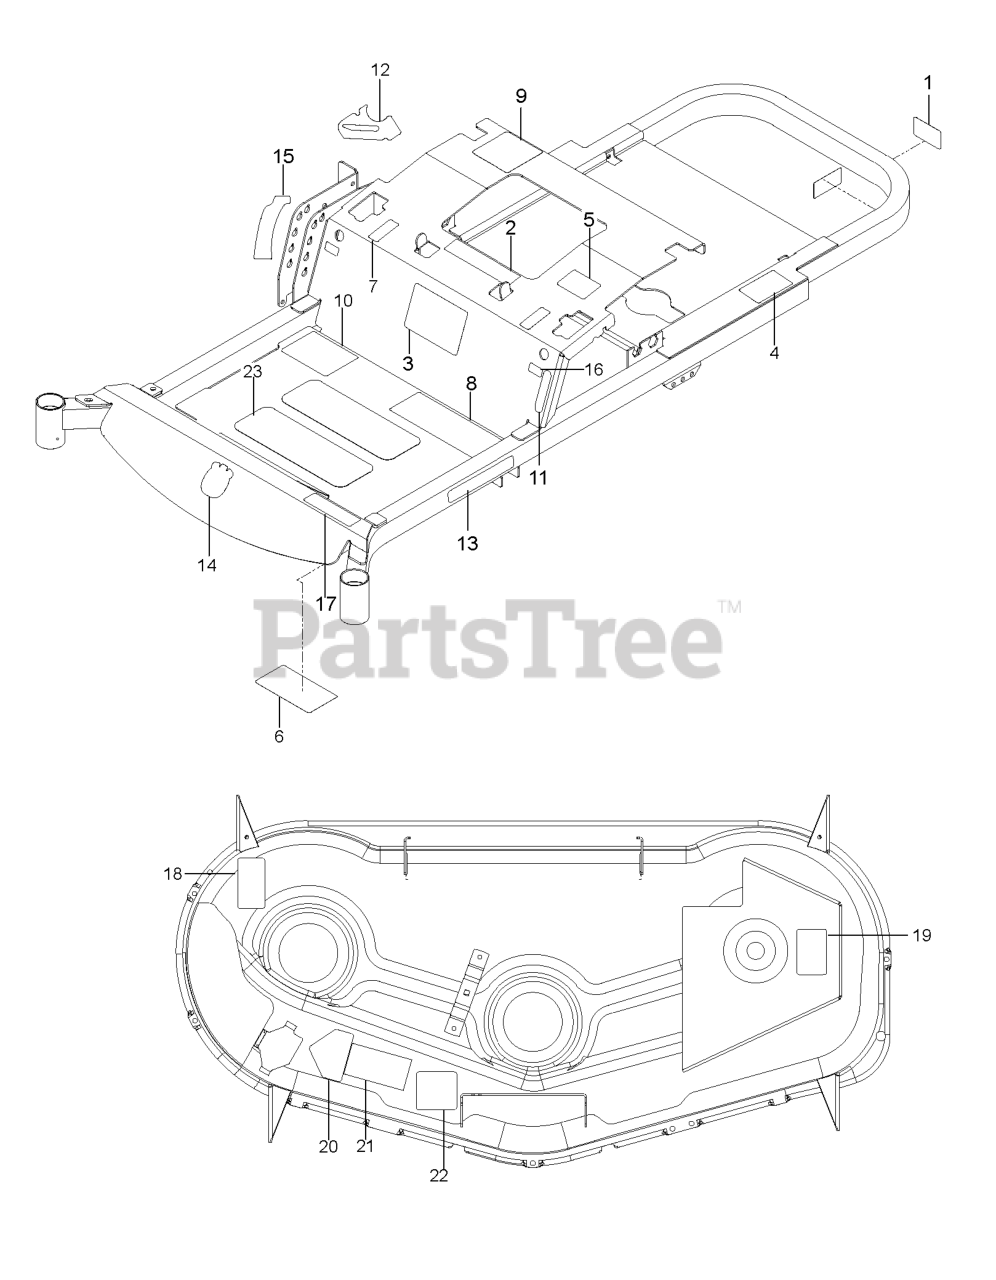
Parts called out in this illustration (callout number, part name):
1	DECAL, PROP. 65
2	EURO DECAL-BATTERY WARNIN6
3	DECAL, START
4	DECAL, DO NOT TOW
5	DECAL, EXITING MOWER
6	DECAL, SERVICE
7	DECAL, MOTION CONTROL
8	DECAL, SAFETY WARNING
9	DECAL, CUSTOMER RESPNSIBILITY
10	DECAL, WARNING
11	DECAL, PARK BRAKE
12	DECAL, IGNITION CONSOLE
13	DECAL.HOOD.LOGO.ORANGE.HUSQVAR
14	DECAL, CROWN H 70MM
15	DECAL, HEIGHT
16	DECAL, F.S.T.
17	DECAL, RZ5422
18	DECAL, CAUTION
19	DECAL, NO STEP
20	DECAL, CPSC
21	DECAL, EURO SEVERING
22	DECAL, BELT ROUTING
23	ANTI-SKID PAD
